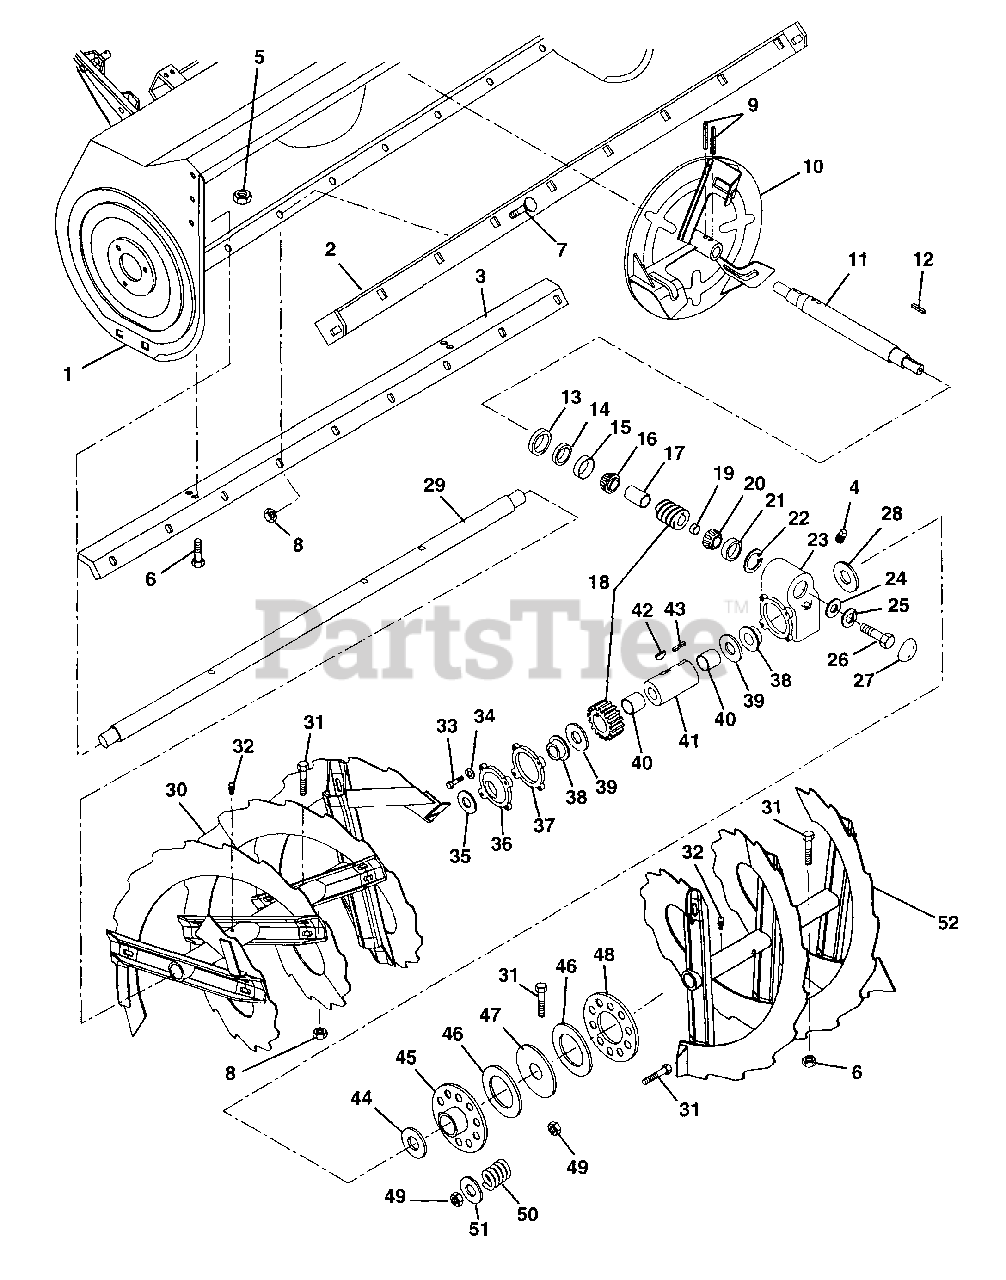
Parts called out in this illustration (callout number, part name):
1	48 Auger/16 Impeller Housing
2	Scraper Blade
3	Scraper Blade Brace
4	Pipe Plug
5	Nut-Locking Center .375-16
6	Bolt-Hex .38-16 x .75 Grade 5
7	Bolt-Round Head Square Neck .31-18 x .75 Grade 2
8	Nut-Locking-Center .31-18
9	Pin-Roll .313 x 1.75
10	Fan 16 Inch
11	Worm Shaft
12	Key-Square .188 x 1.00 x .188
13	Adjustment Plug
14	Seal 1.125 x 1.375 x .125
15	Bearing-Cup Point 1.980 x .420
16	Bearing-Cone 1.0 x .58
17	Bearing Spacer
18	Worm & Gear Service Assembly
19	Bearing Spacer 1.12 x 1.52 x .5
20	Bearing-Cone .750 x .61
21	Bearing-Cup Point 1.78 x .475
22	Ring-Retaining-Internal 1.781 x .062
23	Gear Case
24	Washer-Flat-Steel .328 x 1.0 x .094
25	Washer-Locking .31 x .078
26	Bolt-Hex .31-18 x .75 Grade 5
27	Dust Cap
28	Seal 1.625 x 2.125 x .250
29	48 Inch Rake Shaft
30	Rake, Right Hand-48
31	Bolt-Hex .31-18 x 2.00 Grade 5
32	Fitting-Lube .25-28 x .256
33	Bolt-Hex .25-20 x .75 Grade 5
34	Washer-Locking External .262 x .502 x .026
35	Seal 1.625 x 2.125 x .250
36	Gear Case Cover
37	Gasket
38	Bushing-Flange 1.625 x 1.87 x 1.68 x 2.250
39	Washer-Flat-Steel 1.625 x 2.500 x .012
40	Bushing-Sleeve 1.125 x 1.125 x 1.000
41	Gear Case Shaft
42	Key-Feather .25 x .875 x .25
43	Key-Square .25 x .625 x .375
44	Washer-Flat-Steel 1.625 x 2.500 x .060
45	Driver
46	Friction Disc
47	Driven Plate
48	Pressure Plate
49	Nut-Locking-Center .31-18
50	Spring-Comp .156 x .665 x .75
51	Washer-Flat-Steel .344 x .688 x .065
52	Rake, Left Hand-48"
